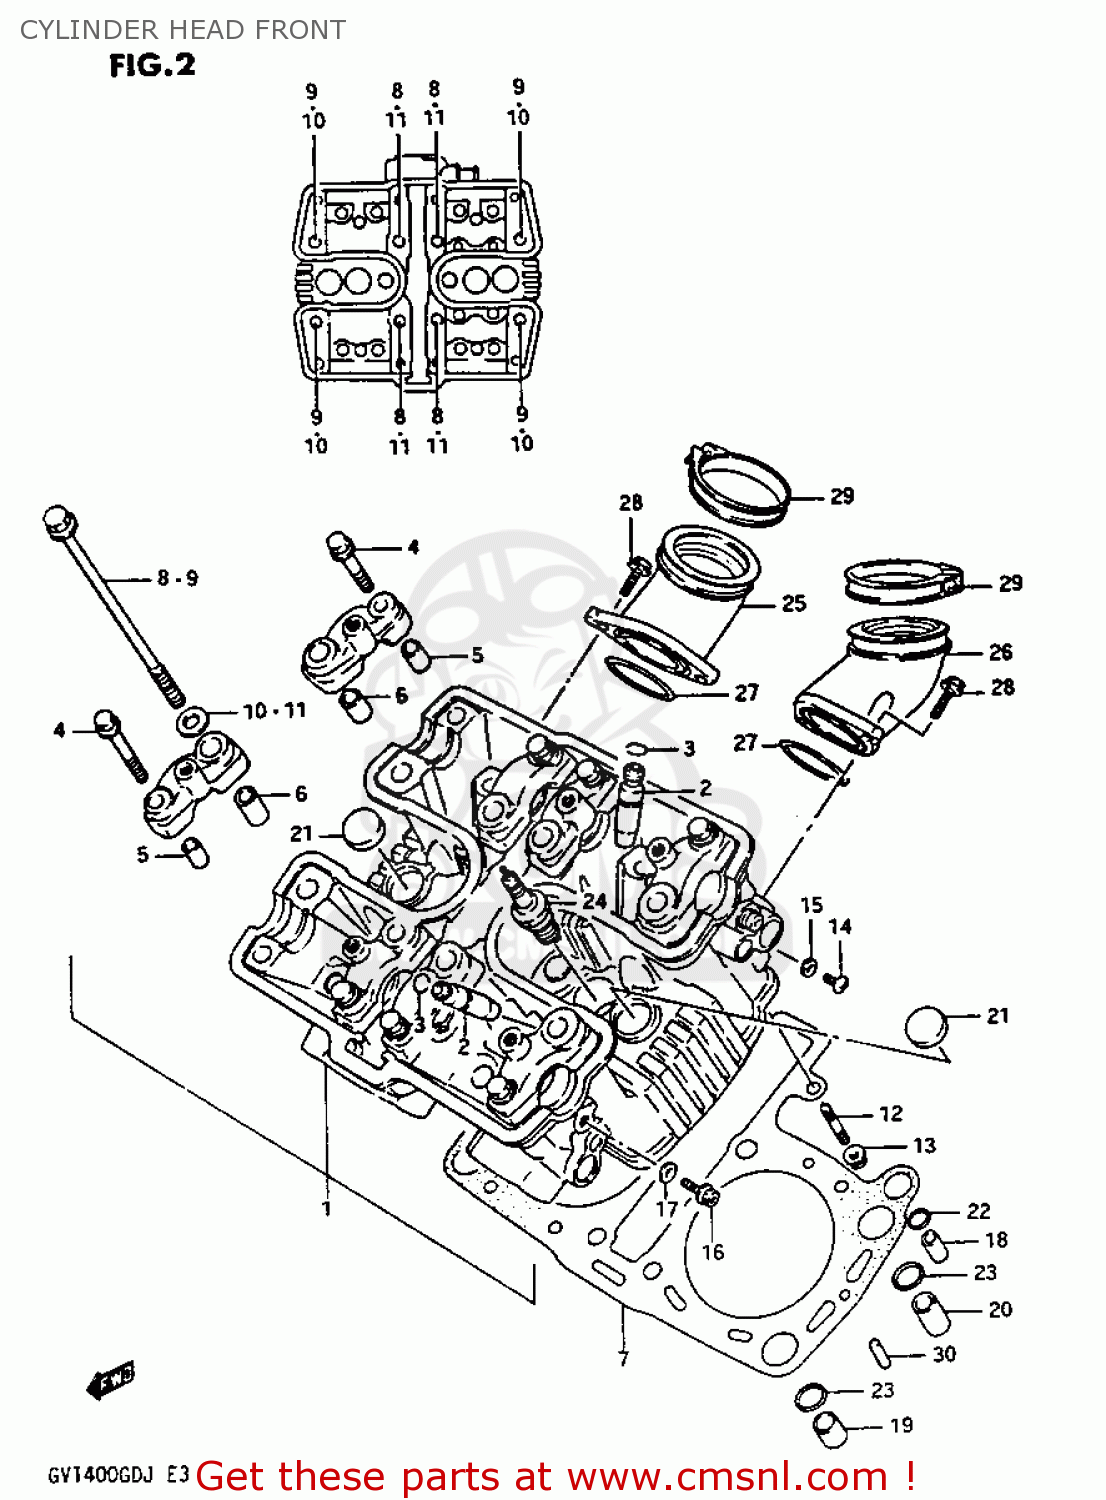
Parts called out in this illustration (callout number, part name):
1	HEAD ASSEMBLY,CYLINDER,FRONT
2	GUIDE,VALVE
3	RING,SNAP
4	BOLT
5	PIN (11X20)(SUS)
6	PIN(10.4X13X22)
7	GASKET,HEAD,FRONT (NAS)
8	BOLT
9	BOLT
10	WASHER
11	WASHER (10X20X2.3)
12	STUD 6X25
13	NUT 6MM
14	SCREW
15	GASKET(5.3X9.3X1.2) (NAS)
16	BOLT
17	GASKET(6.2X13X1.2) (NAS)
18	PIN
19	PIPE
20	PIN
21	PLUG
22	O RING(D:1.9,ID:8.6)
23	O RING(D:1.9,ID:12.6)
24	SPARK PLUG
25	PIPE,INTAKE
26	PIPE,INTAKE
27	O-RING (D:2.4 ID:39.7)
28	BOLT 6X20
29	CLAMP,PIPE
30	PIN
